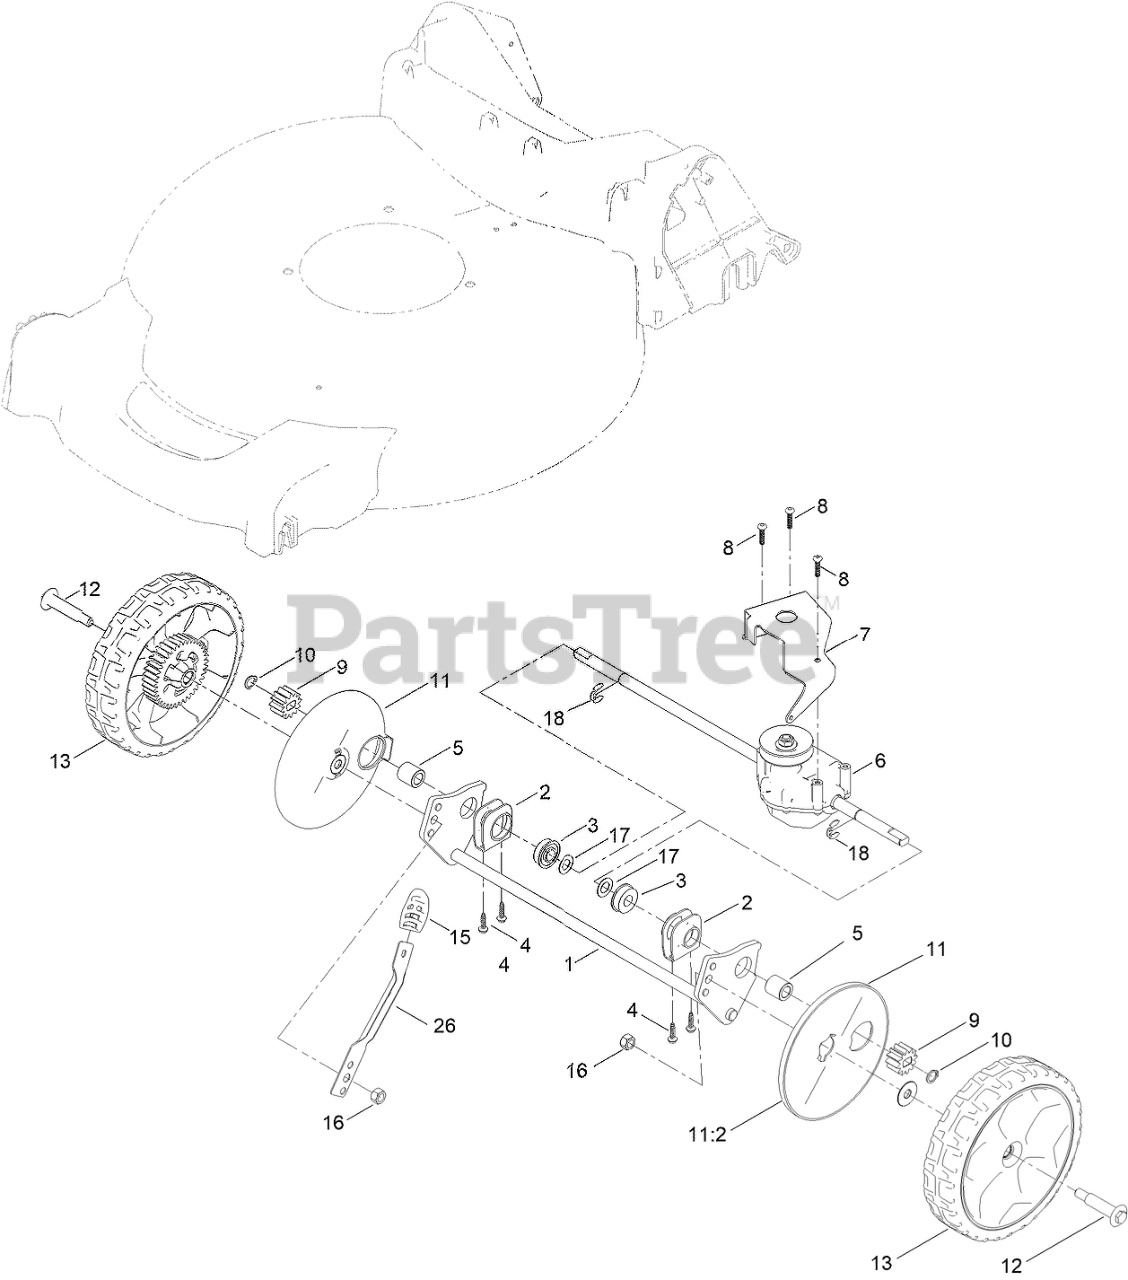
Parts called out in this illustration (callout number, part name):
1	AXLE-REAR
2	RETAINER-BEARING
3	BEARING-BALL
4	SCREW-HWH
5	BUSHING-SLEEVE
6	TRANSMISSION
7	BRACKET-TRANSMISSION
8	SCREW-PLASTITE
9	GEAR-PINION
10	RING-RETAINING
11	WHEEL COVER ASM
11:2	WASHER-STEPPED
12	BOLT-SHOULDER
13	8 INCH WHEEL GEAR ASM
15	KNOB-LEVER, HOC
16	LOCKNUT
17	WASHER-PLAIN
18	RING-RETAINING,CLIP
26	ARM-SPRING
